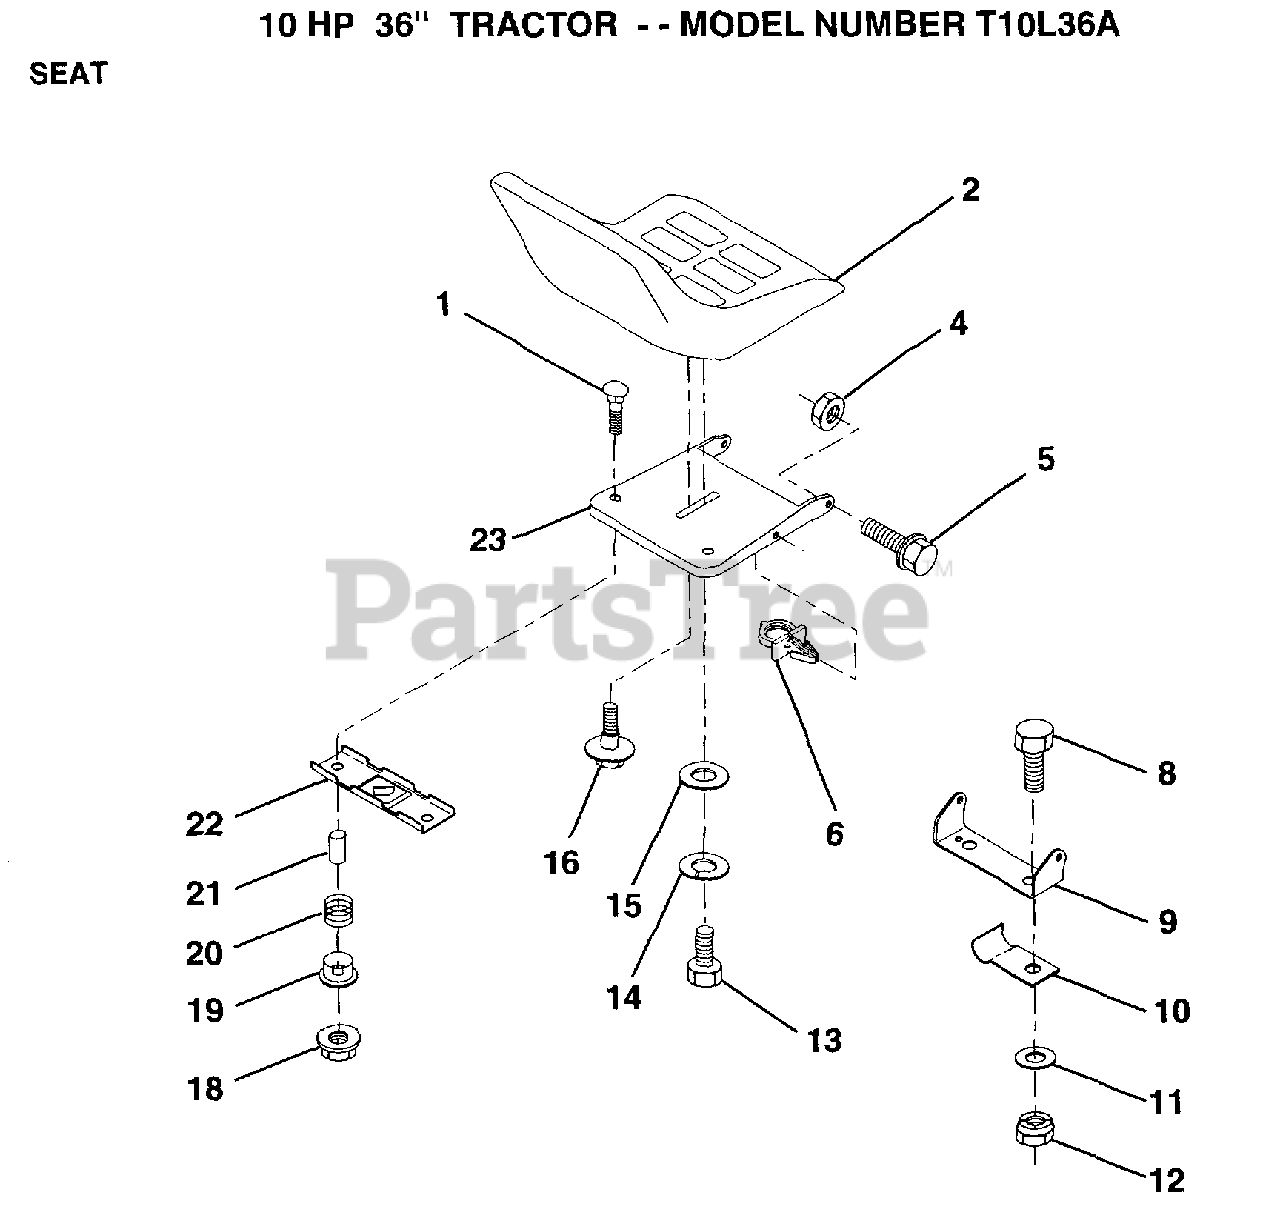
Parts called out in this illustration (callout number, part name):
4	NUT
5	BOLT.SHLD.5/16-18
6	CLIP PUSH - IN
8	BOLT
9	BRACKET PVT SEAT
10	"CLIP,INSULATOR"
11	WASHER
12	NUT
13	BOLT
14	LOCKWASHER
15	WASHER
16	"BOLT,SHOULDER"
19	BUSHING
20	SPRING
21	SPLIT SPACER
22	BRKT SWITCH
